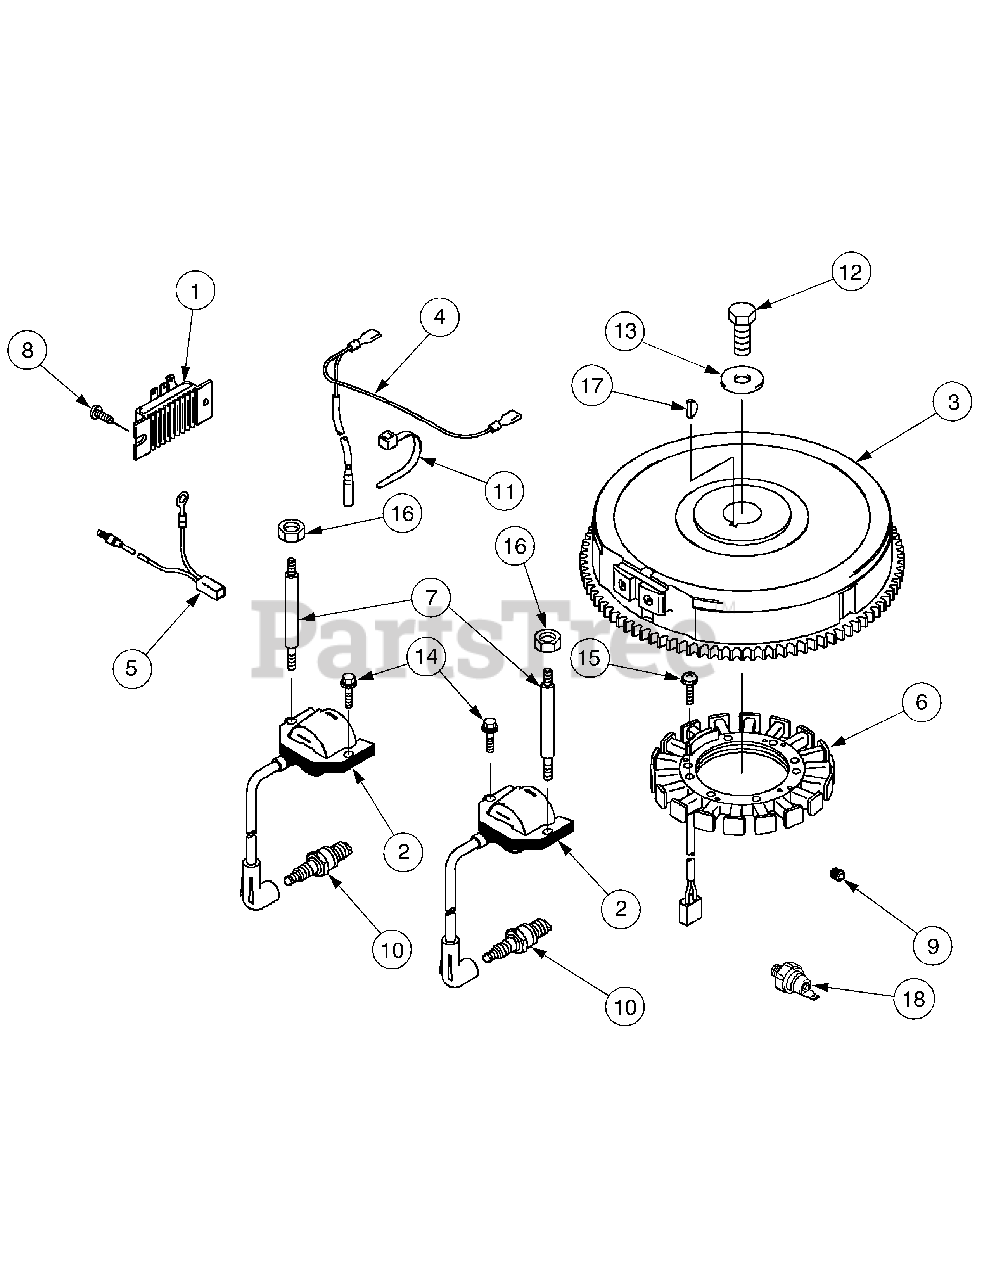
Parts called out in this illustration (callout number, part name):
1	Regulator, Voltage
2	Coil, Ignition
3	Flywheel
6	Coil, Charging
7	Stud
10	Plug, Spark, (NGK), Solid
12	Bolt, 12 x 30
14	Bolt, Flanged
15	Screw, Pan Hd.
16	Nut, Hex
17	Key, Woodruff
18	Switch, Oil Pressure
